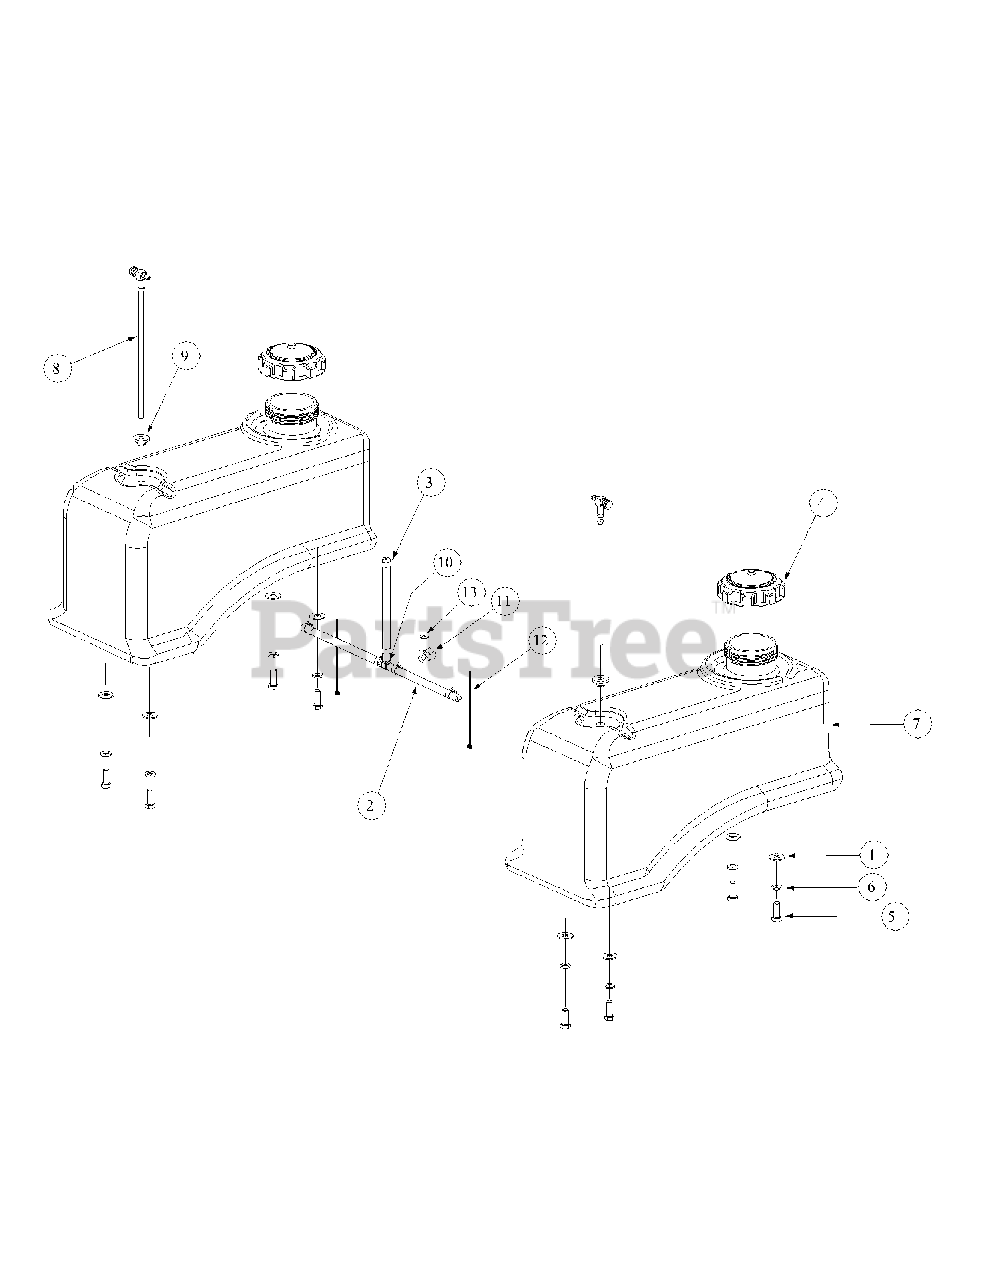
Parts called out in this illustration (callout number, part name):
1	Flat Washer, .406 ID, 1.0 OD, .105
2	Hose, 1/4" Fuel Line 79.5 inches
3	Clamp, Union
4	Fuel Cap, 3.5
5	Hex, Cap Screw, 3/8-16, .88
6	Lock Washer, 3/8
7	Fuel Tank
8	Fuel Fitting
9	Grommet, Fuel Tank
10	Tee Fitting, Fuel
11	Clamp, 1/2 Tubing
12	Cable Tie
13	Flat Washer, 1.4 x .630 x .0515
